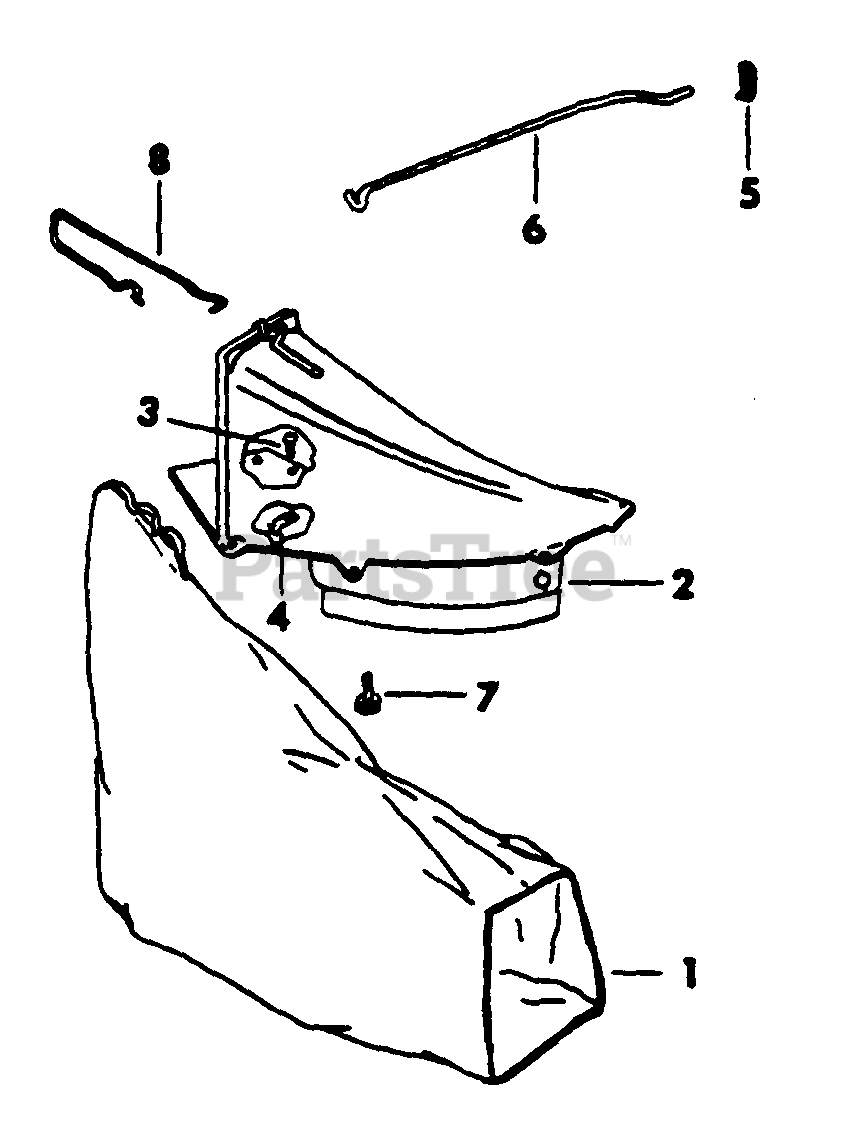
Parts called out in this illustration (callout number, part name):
1	BAG, DELUXE GRASS
6	ROD, GRASS BAG
8	GUARD, WHEEL
